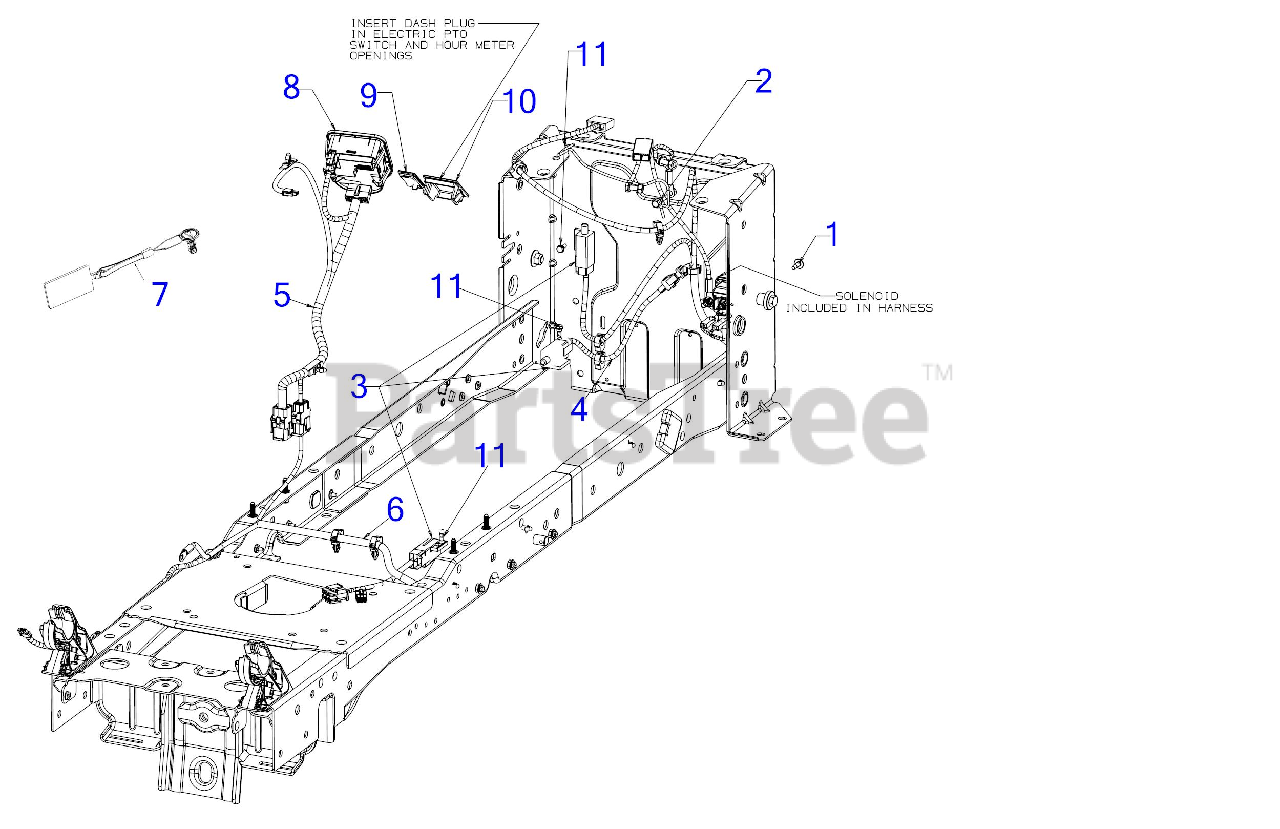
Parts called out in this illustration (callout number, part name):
1	SCREW M6-1 x .625
2	SCREW 1/4-20X.625
3	INTERLOCK SWITCH (NO/NC)
4	REVERSE HARNESS
5	DASH HARNESS M-PTO/PBS/EFI/RMC
6	MAIN HARNESS M-PTO/PBS/EFI
7	PBS KEY
8	MODULE-PBS/HRMTR/SVC MNDR/BT
10	DASH HOUR METER PLUG
11	SHOULDER SCREW
